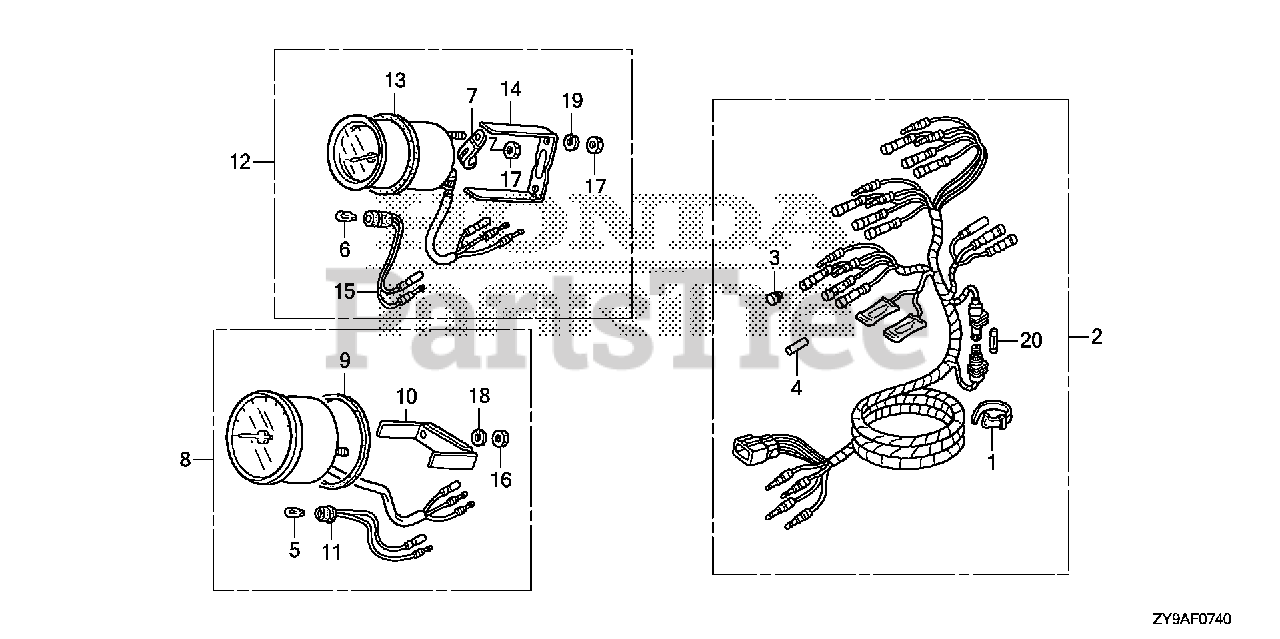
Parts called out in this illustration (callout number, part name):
1	BAND B1, CABLE Use up to Frame SN 1001879.
2	HARNESS ASSY., METER (A)
3	PLUG, CONNECTOR (INNER) (TROLLING CONTROL)
4	PLUG, CONNECTOR (OUTER) (ENGINE NO.)
5	BULB, WEDGE BASE (T10) (12V 1.7W) (STANLEY)
6	BULB, WEDGE BASE (12V1.7W) (TOSHIBA)
7	CLAMP
8	TACHOMETER ASSY.
9	GASKET
10	BRACKET (TO 1015209) (FROM 1015210)
11	SOCKET (TO 1015209) (FROM 1015210)
12	METER ASSY., TRIM
13	GASKET (TO 1015209) (FROM 1015210)
14	BRACKET (TO 1015209) (FROM 1015210)
15	SOCKET (TO 1015209) (FROM 1015210)
16	NUT, HEX. (5MM)
17	NUT, HEX. (4MM)
18	WASHER, SPRING (5MM)
19	WASHER, SPRING (4MM)
20	FUSE A (10A)
